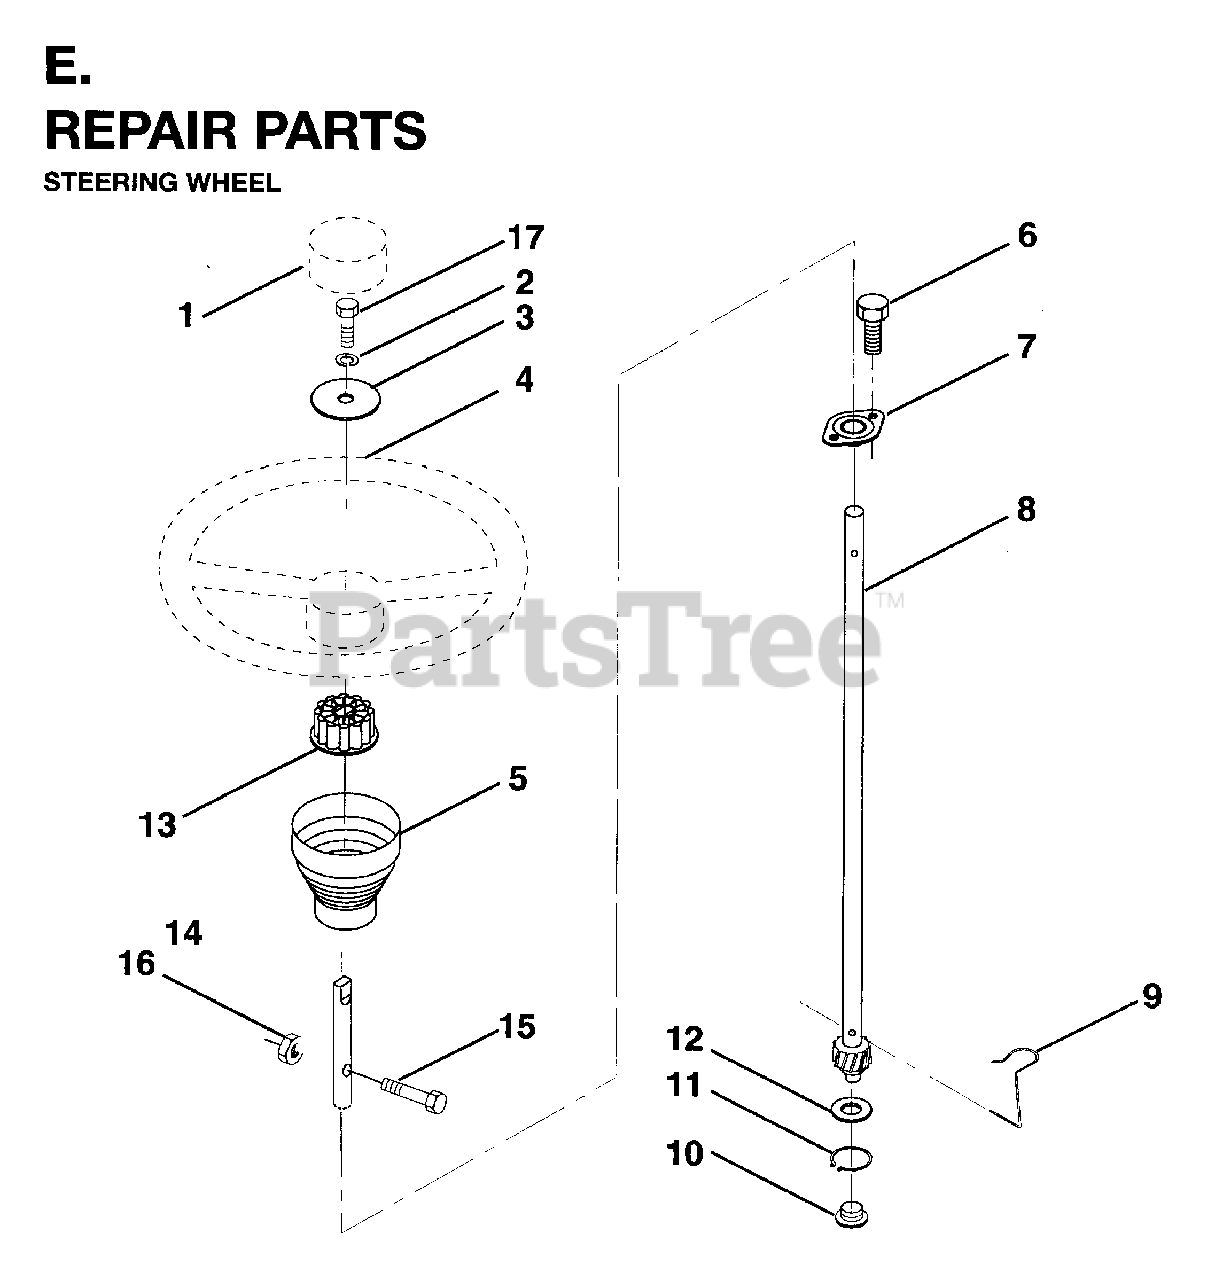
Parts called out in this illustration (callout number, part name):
2	NUT
3	WASHER T
7	BUSHING-STRG LT
8	STEERING SHAFT
9	STEERING CLIP
10	BUSHING STEER LWR
13	ADAPTER-WHEEL LT
14	SHAFT EXTENSION
15	BOLT.5/16-18X1-1/4 FULL.THREAD
16	NUT.71038.31-18.HEX.NYLOCK
